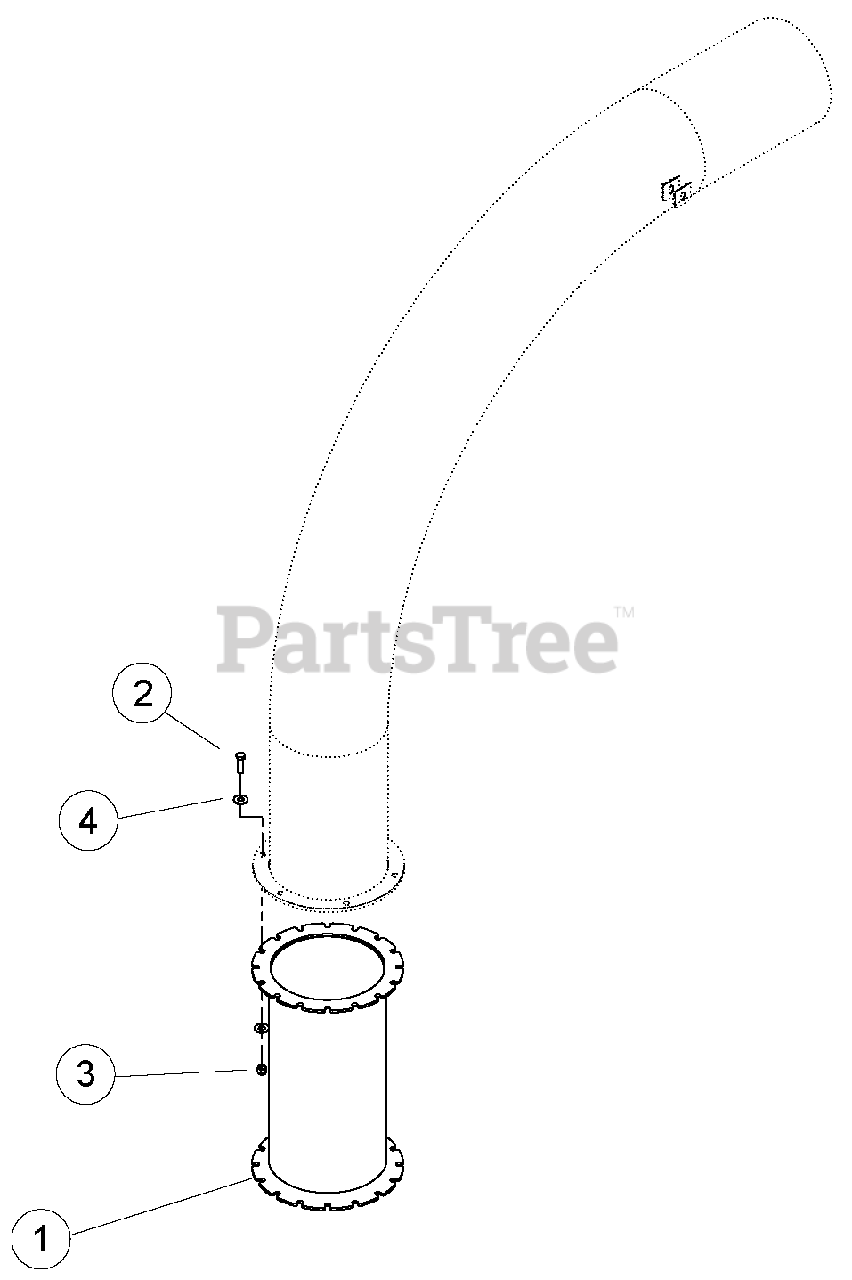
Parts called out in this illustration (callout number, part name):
1	WELDMENT, CHUTE EXTENSION
2	BOLT, 3/8 X 1-1/4"HHCS GR5 ZP
3	NUT, 3/8" NE NYLOCK ZP
4	WASHER, 3/8" FLAT ZP
